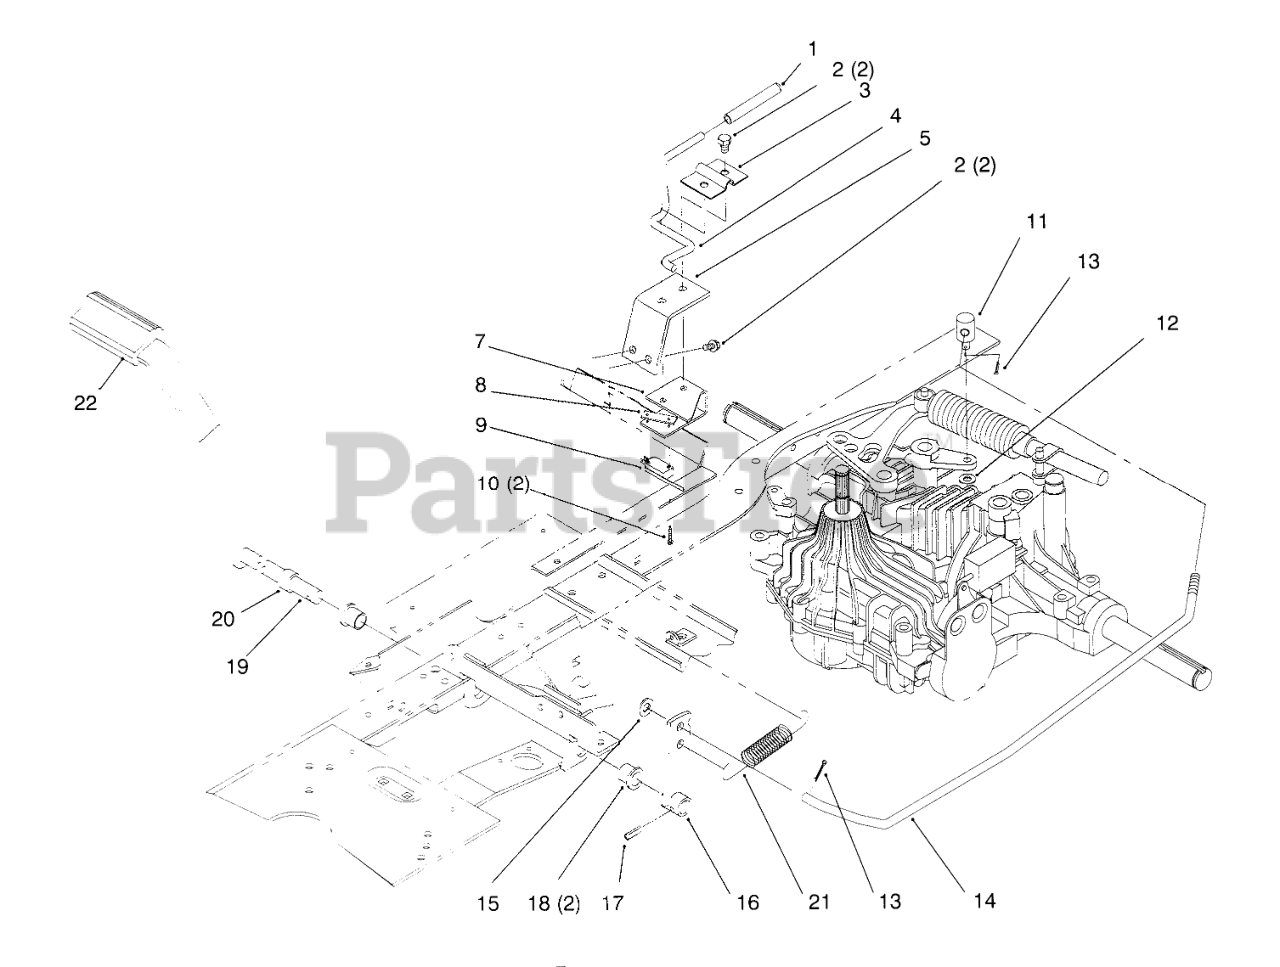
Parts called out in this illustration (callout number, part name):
1	Grip-Parking Brake (Only On: 72043,72063,72103)
2	Screw-HH (Only On: 72043,72063,72103)
3	Bracket-Park Brake (Only On: 72043,72063,72103)
4	Rod-Park Brake (Only On: 72043,72063,72103)
5	Support-Park Brake (Only On: 72043,72063,72103)
7	Bracket - Micro Sw (Only On: 72043.72063)
8	Nut-Speed(Only On 72043,72063)
9	Switch-Micro Sw (Only On:72043,72063)
10	Screw (Only On: 72043, 72063)
11	Trunnion-Brake (Only On: 72043,72063,72103)
12	Washer-Flat (Only On: 72043,72063,72103)
13	Pin-Cotter (Only On: 72043,72063,72103)
14	Rod-Brake (Only On: 72043,72063,72103)
15	Washer-Flat (Only On: 72043,72063,72103)
16	Lever-Brake (Only On: 72043,72063,72103)
17	Pin-Spring (Only On:72043,72063,72103)
18	Bushing-Flange (Only On: 72043,72063,72103)
19	Pedal-Brake (Only On: 72043,72063,72103)
20	Spacer-Brake (Only On: 72043,72063,72103)
21	Spring-Extension (Only On: 72043,72063,72103)
22	Pad-Pedal (Only On: 72043,72063,72103)
